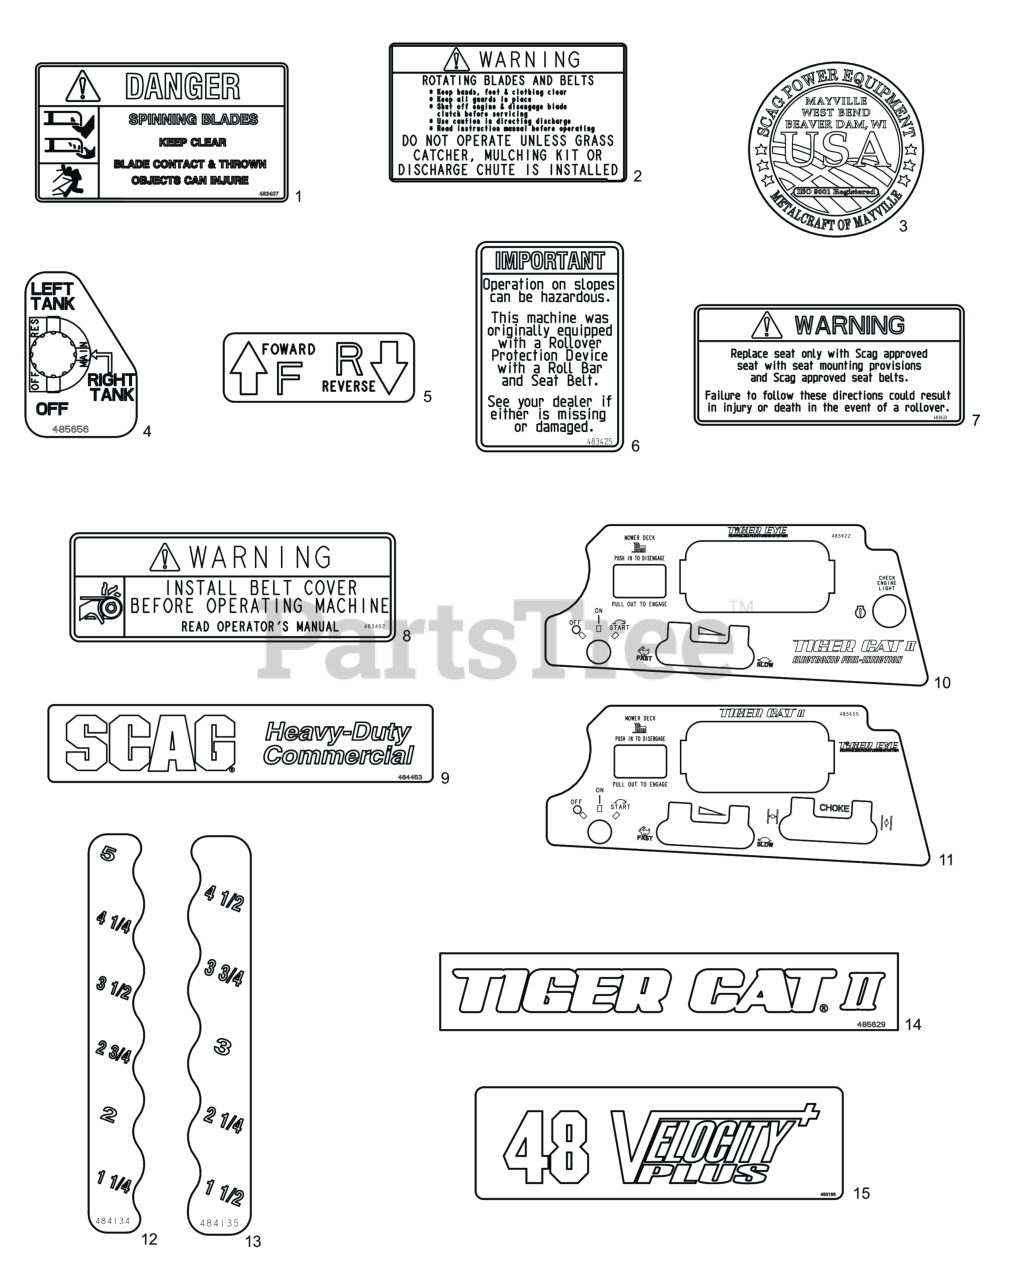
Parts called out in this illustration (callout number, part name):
1	Decal, Danger-Spinning Blades
2	Decal, Warning - Rotating Blades
3	Decal, Metalcraft - USA
4	Decal, Fuel Valve Position
5	Decal, Traction Control
6	Decal, ROPS
7	Decal, Seat Replacement
8	Decal, Warning - Belt Cover
9	Decal, Scag Heavy Duty Commercial
10	Decal, Instrument Panel - EFI
10	Decal, Instrument Panel - Kawasaki EFI
11	Decal, Instrument Panel
12	Decal, Deck Height - LH
13	Decal, Deck Height - RH
14	Decal, Tiger CatII
15	DECAL, VELOCITY PLUS - 48
